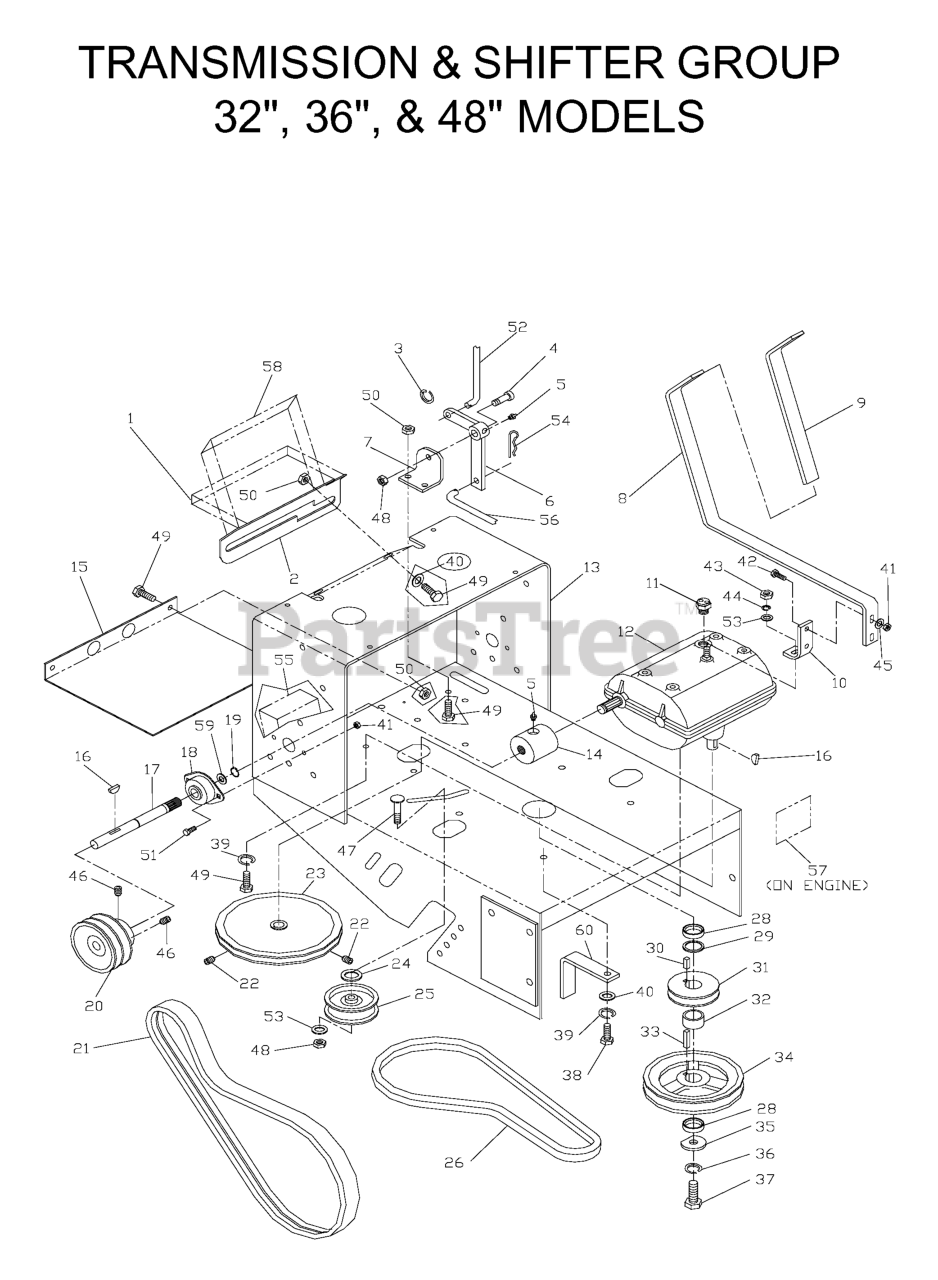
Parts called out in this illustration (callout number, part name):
1	DECAL, SHIFTER
2	SHIFTER PLATE
4	SB 12C X 34
5	ZERK
8	SHIFTER ARM
9	SHIFTER GRIP
10	SHIFTER BRACKET
11	SWITCH, TRANS
12	TRANSMISSION WB
13	REAR DECK W/DECALS
15	LOWER BELT SHIELD
16	KEY, #9 WOODRUFF
17	DRIVE SHAFT
19	RETAINER RING
20	PULLEY, DRIVE (36 & 48)
21	BELT, DRIVE (36 & 48)
22	SETSCREW, 1/4-20 NYLOC
23	PULLEY, INPUT
24	WASHER 1/2 FLAT
25	IDLER PULLEY
26	BELT, TRANSMISSION
27	BELT GUIDE
29	BUSHING, 10GA MACHINERY
30	SQUARE KEY - 1/4 X .5
33	KEY 1/4 SQ X 1 1/8
34	PULLEY, ENGINE
35	SPINDLE WASHER
36	WASHER 7/16 LOCK
37	HCS M10-1.5X35MM
38	HTB M8-1.125 X 25MM
39	WASHER.LOCK.HVY.HLCL.SPR.5/16
40	WASHER 5/16 FLAT
41	NUT 1/4C CENTER LOCK
42	HCS 1/4C X 1
44	SLW 3/8 STD
45	WASHER 1/4 FLAT
46	SET SCREW 5/16 NYLOC
47	RHSNB 3/8C X 2
48	NUT 3/8C CENTERBLOCK
49	HCS 5/16C X 3/4
50	NUT 5/16C CENTERLOCK
51	HCS 1/4C X 5/8
53	WASHER 3/8 FLAT
54	HAIRPIN #4
55	DECAL, DANGER
56	BLADE ROD 48"
57	DECAL, EXHAUST
58	DECAL, CLUTCH
60	BELT GUIDE - LONG
61	BELT GUIDE, SHORT
539100141	HCS 7/16F X 1 1/2
539100567	HCS M8-1.25 X 30MM
539102048	BLADE ROD 36"
539102149	DRIVE BELT (32)
539102154	DRIVE PULLEY (32)
